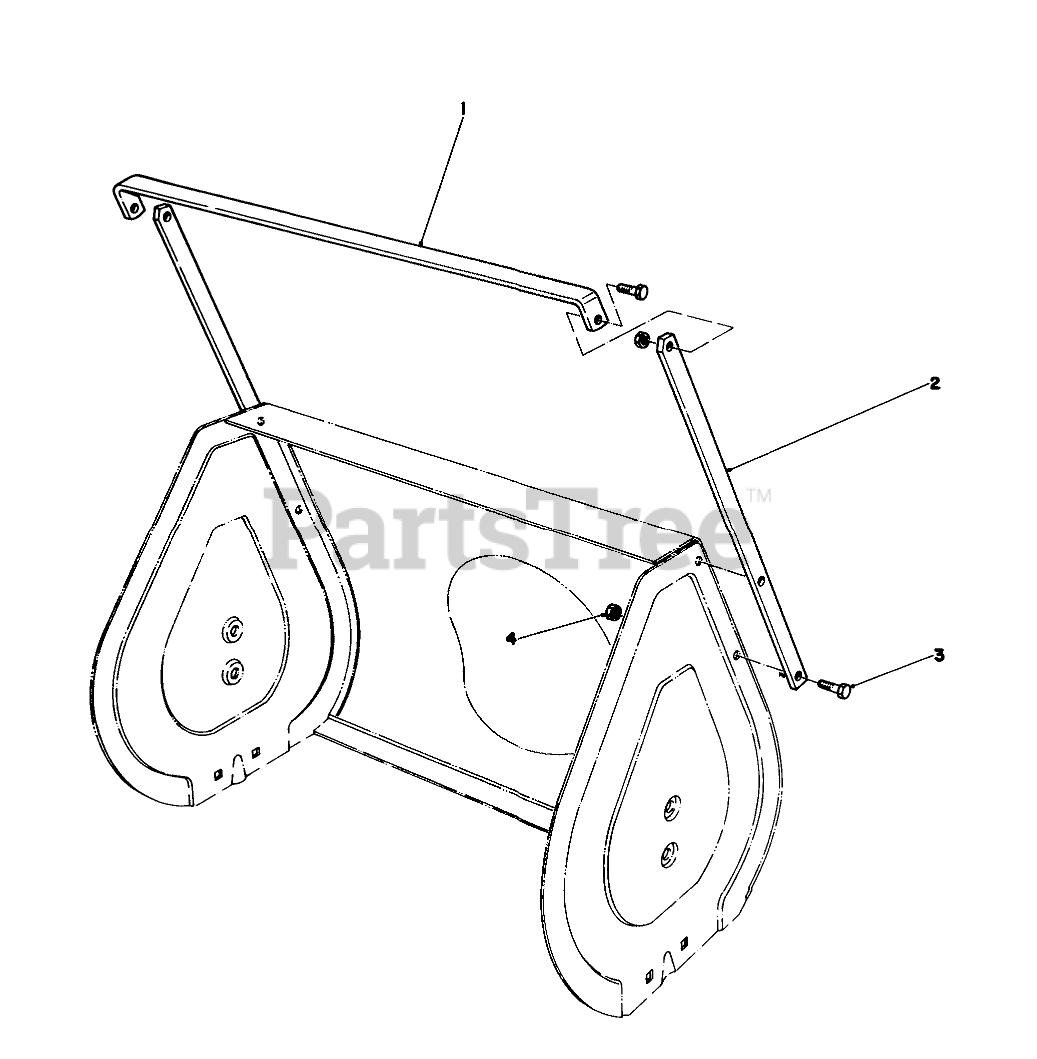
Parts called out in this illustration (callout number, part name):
1	Drift Breaker-Top
2	Drift Breaker-Side
3	SCREW-HH
4	NUT-LOCK, NI
